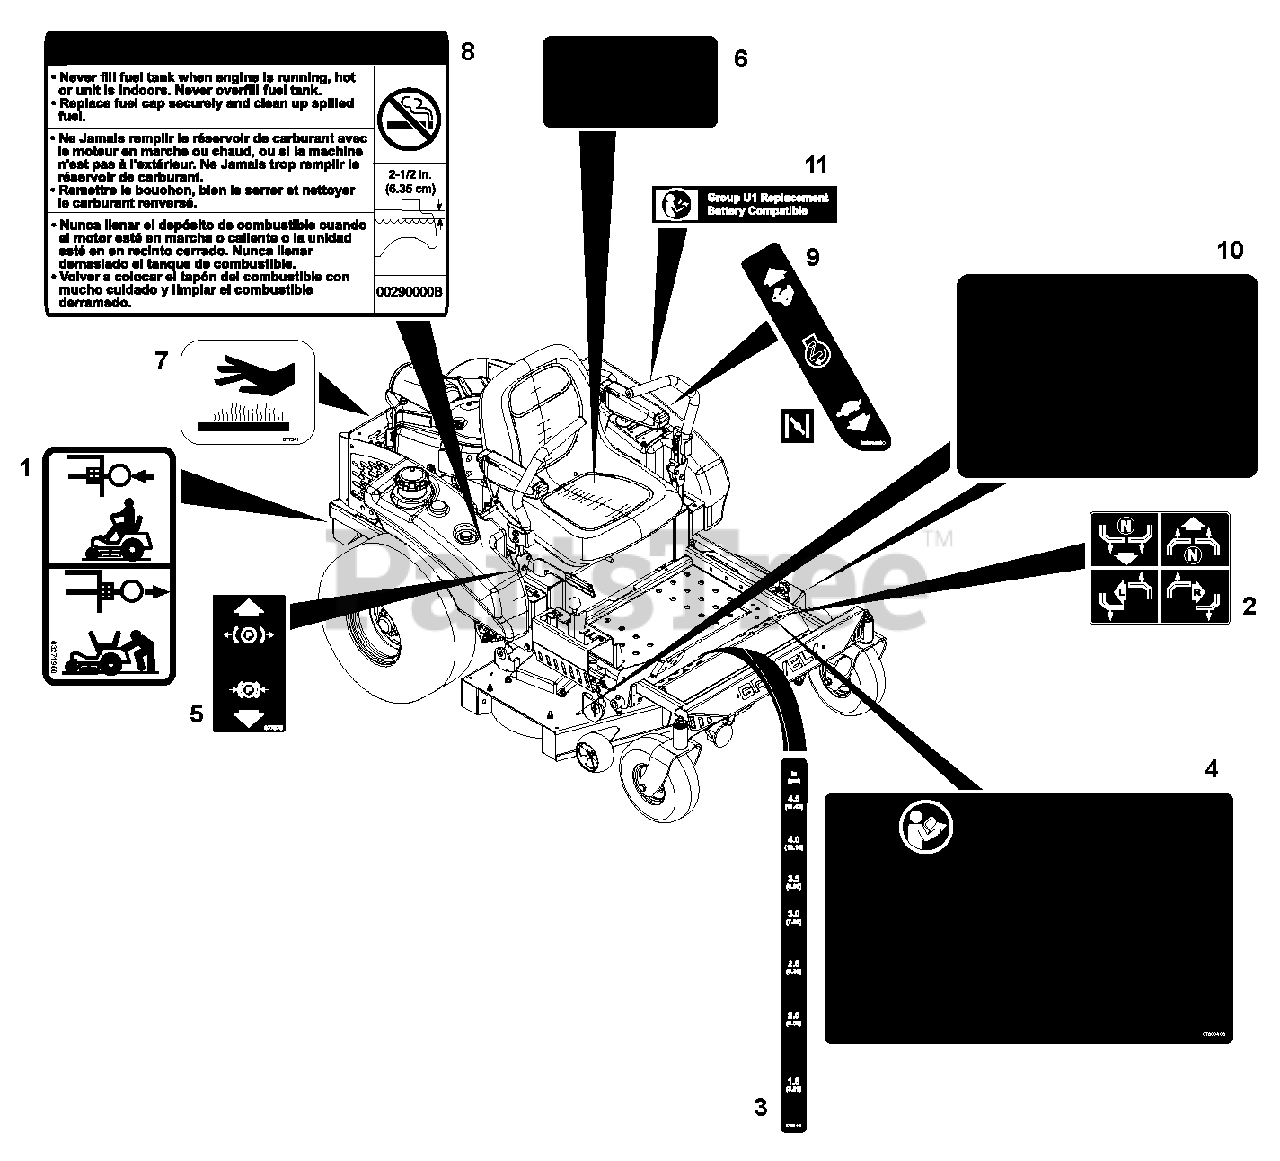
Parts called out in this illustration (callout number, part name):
1	Decal, Transmission Disconnect
2	Decal, Instructional Steering
3	Decal, Cut Height
4	Decal, Safety, Main
5	Decal, Parking Brake Lever
6	Decal, Safety, Guarding
7	Decal, Hot Surface
8	Decal, Fuel Warning
9	Decal, Control
10	Decal, Mower Deck Safety
11	Decal, Battery Replacement
